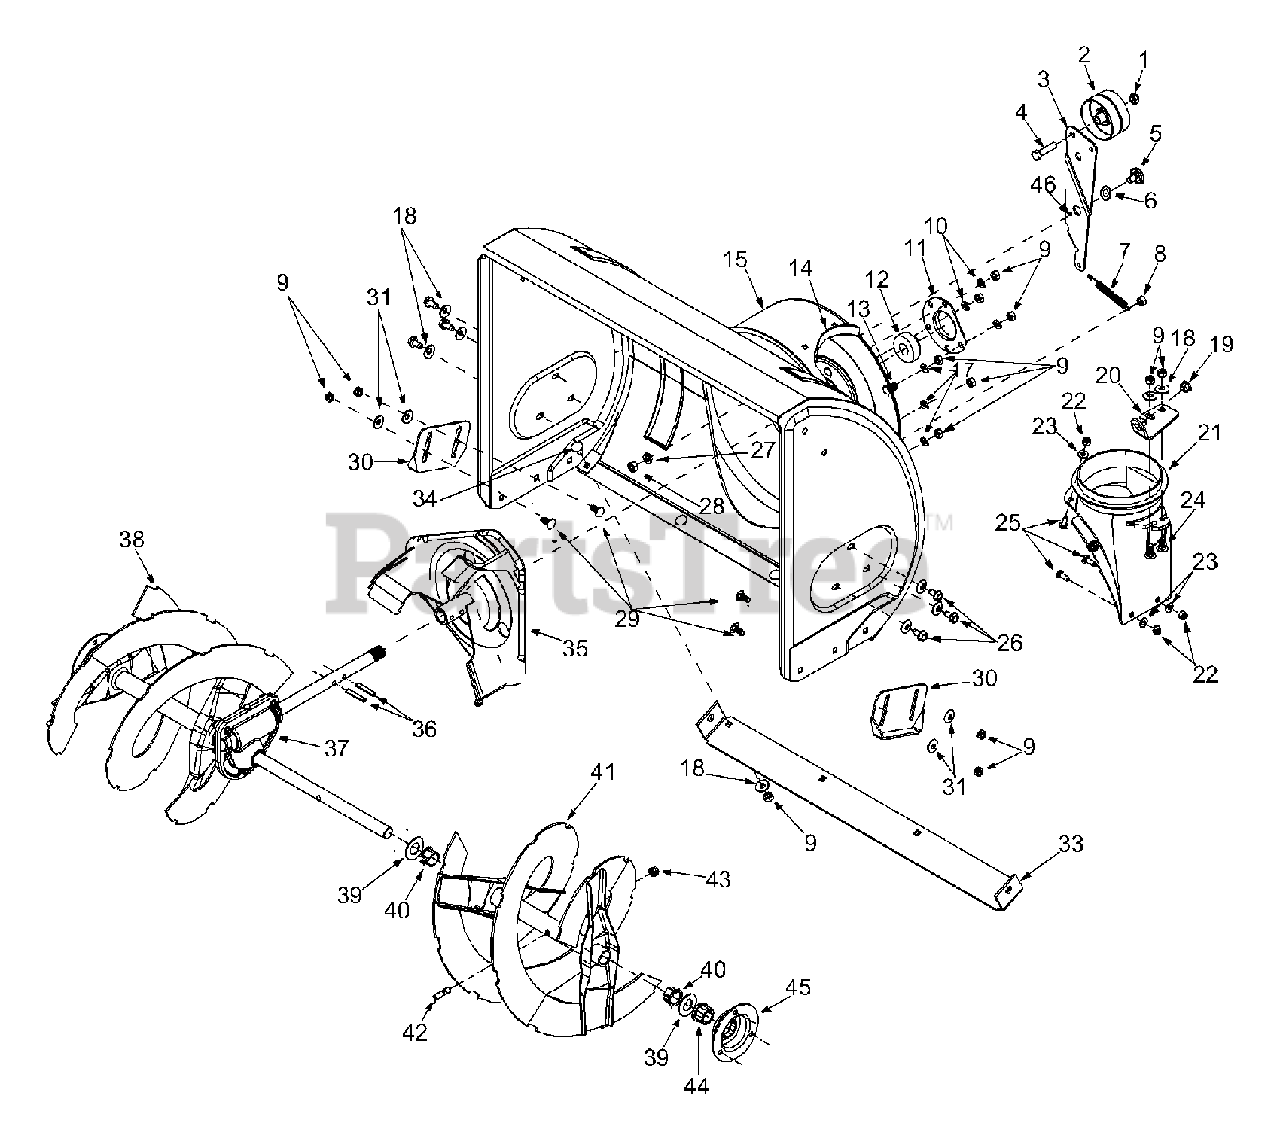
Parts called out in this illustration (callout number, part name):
1	Lock Jam Nut 3/8-24
2	Flat Idler
4	Hex Cap Screw 3/8-24 x 1.50
5	Shoulder Screw
6	Flat Washer
7	Extension Spring
8	Hex Nut 5/16-18
9	Hex Nut 5/16-18
10	Lock Washer 5/16
11	Housing
12	Ball Bearing
13	Carriage Bolt 5/16-18
18	Bell Washer
19	Bushing
21	Chute Adapter
22	Hex Lock Nut 1/4-20
23	Flat Washer
24	Carriage Bolt
25	Carriage Screw 1/4-20 x .75
26	Hex Washer Screw 5/16-18
27	Lock Washer 3/8
28	Hex Nut 3/8-16
29	Carriage Bolt 5/16-18 x .75
31	Bell Washer
34	Carriage Bolt 5/16-18 x .62
37	22" Gear Assembly
40	Flange Bushing
42	Shear Bolt 5/16-18 x 1.5
43	Lock Nut 5/16-18
44	Hex Flange Bearing
46	Grease
